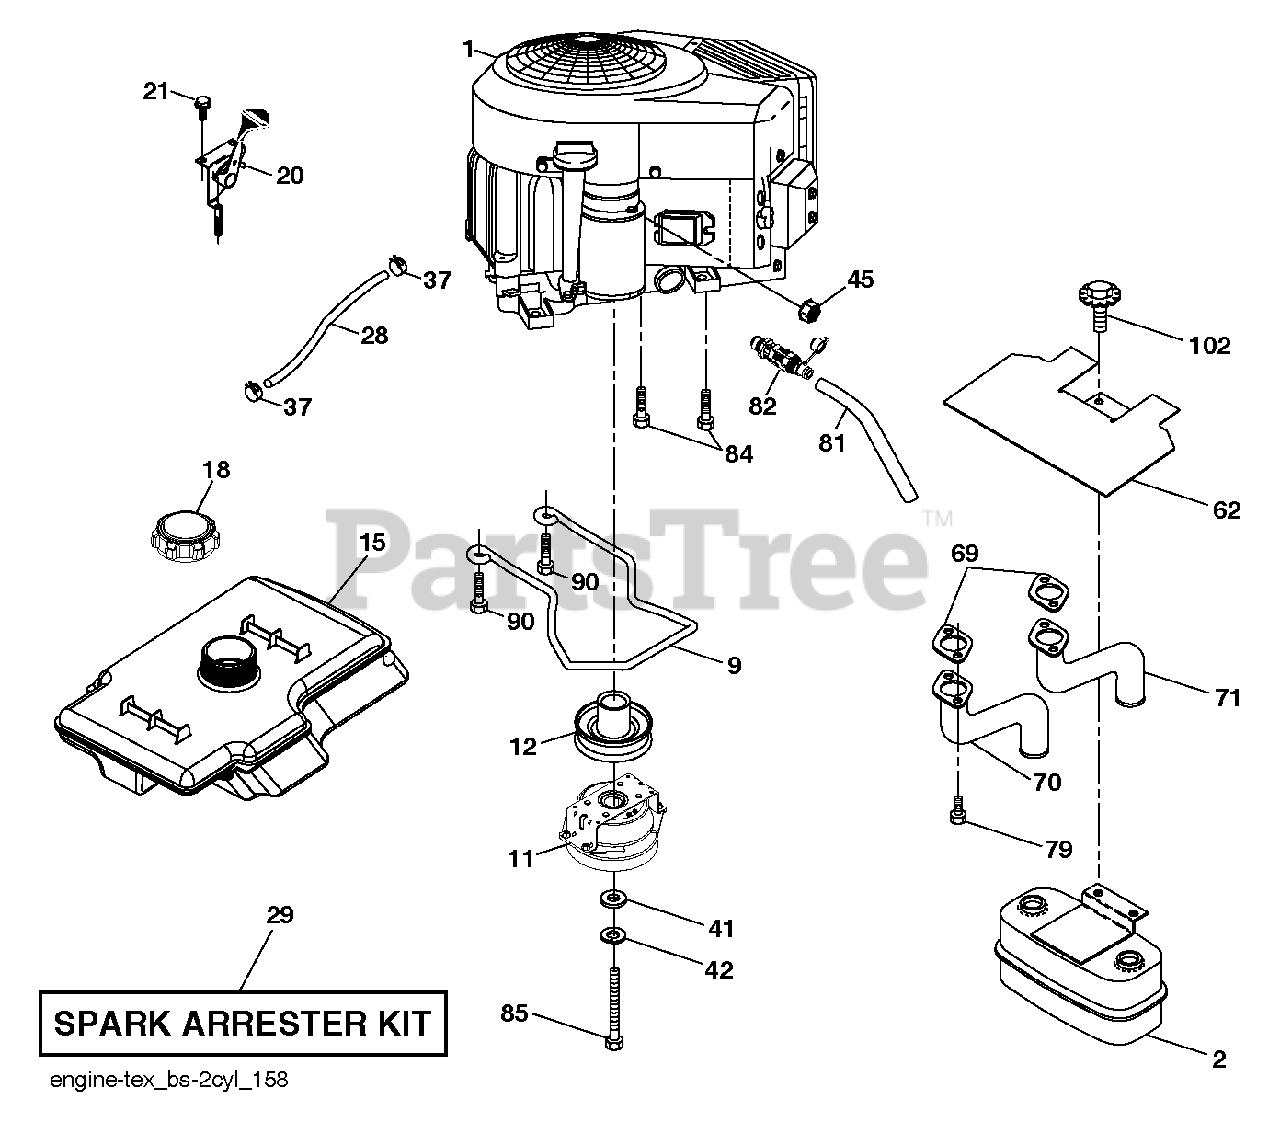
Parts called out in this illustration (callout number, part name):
2	MUFFLER.ASM.TWN.EXTNDED.DFLCTR
9	KEEPER.BELT.ENG.4.25"2.BLT.431
11	CLUTCH.OGURA.4.4PD.GT1.5-EH13V
12	PULLEY.ENGINE.TUFFTORQ
15	FUEL TANK
18	CAP.ASSY.FUEL.3".N-EPA.BLK.428
20	THROTTLE.COBRA.38"READSTART.BK
21	SCREW.#10 X 0.750.BOS
28	REPL BY 532 00 85-43
29	KIT.SPARK ARRESTOR 794945 B&S
37	HOSE CLAMP
42	WASHER 7/16 LOCK
45	NUT
62	SHIELD.HEAT.MUFFLER
69	GASKET.MUFFLER
70	EXHAUST.TUBE.LH.BS/TWIN
71	EXHAUST.TUBE.RH.B&S.TWIN.INTEK
79	SCREW.SOCKET.HEAD.5/16-18
81	TUBE, DRAIN OIL ASM.
82	VALUE.OIL.DRAIN
84	SCREW.3/8-16
85	CLUTCH BOLT7/16-20X3.5 GR524HR
90	SCREW 3/8-16X1
102	SCREW
